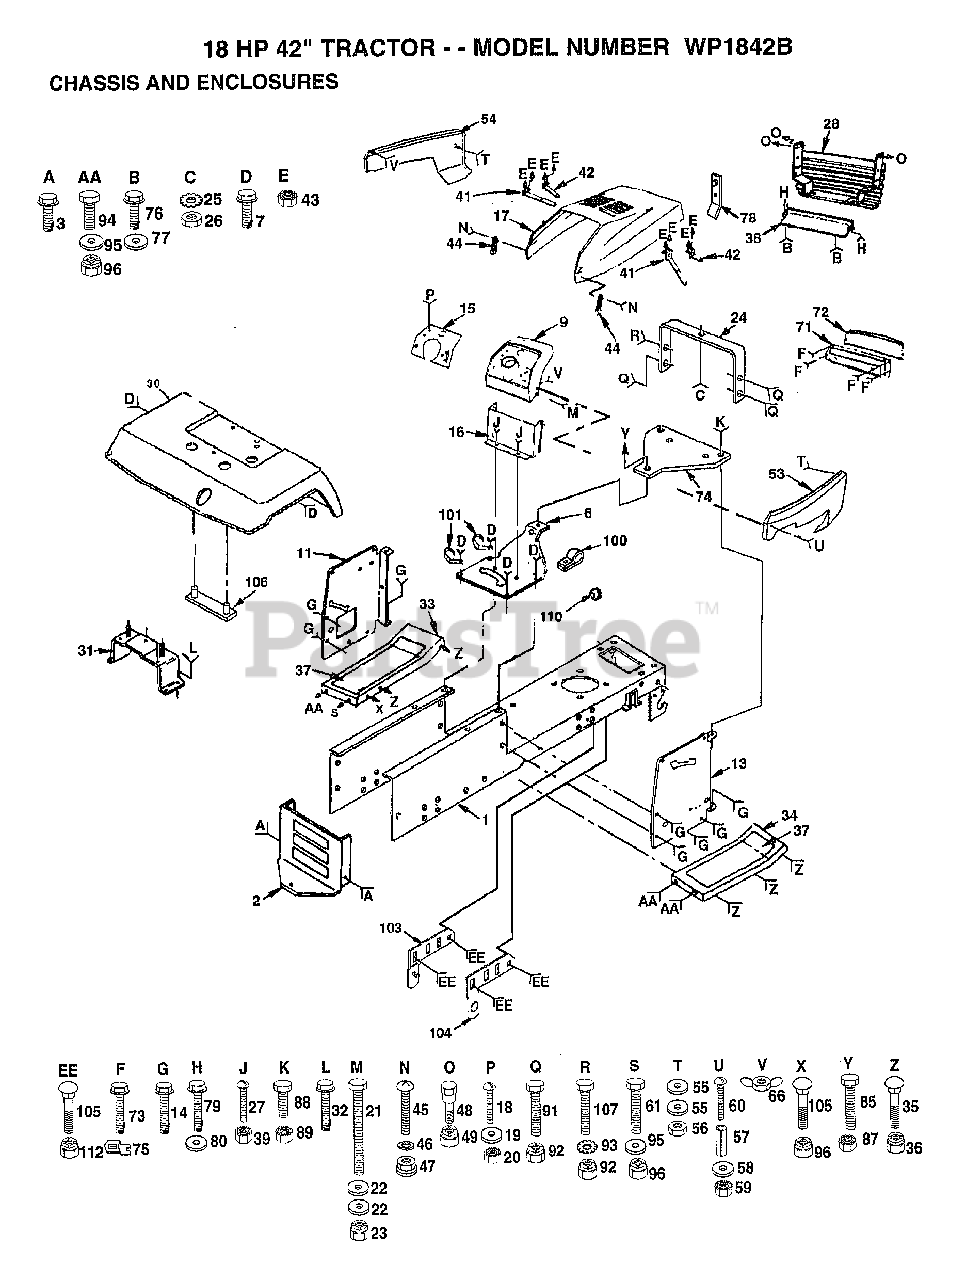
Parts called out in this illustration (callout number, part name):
3	SCREW
6	SADDLE. 6SP
7	SCREW LT
11	PANEL.DASH.LH
14	SCREW
18	SCREW
19	WASHER
22	WASHER
24	SUPPORT ASS'Y
27	SCREW
30	FENDER
31	BRKT.ASM.FENDER
32	SCREW
35	BOLT
37	FOOTREST PAD
43	NUT
44	HOOD LATCH T
45	SCREW
46	LOCKWASHER
47	WELDNUT
54	"PANEL,SIDE LH"
55	WASHER PM
57	SPACER LT
58	WASHER
60	SCREW
72	LENS LT
75	"""J"" FASTENER LT"
76	SCREW
77	WASHER
79	SCREW HEX CRT
80	WASHER
88	BOLT
93	LOCKWASHER
95	WASHER
100	CLIP T
101	"CLIP,INSULATOR"
103	PIVOT BRKT LH
104	PIVOT BRKT RH
112	NUT
